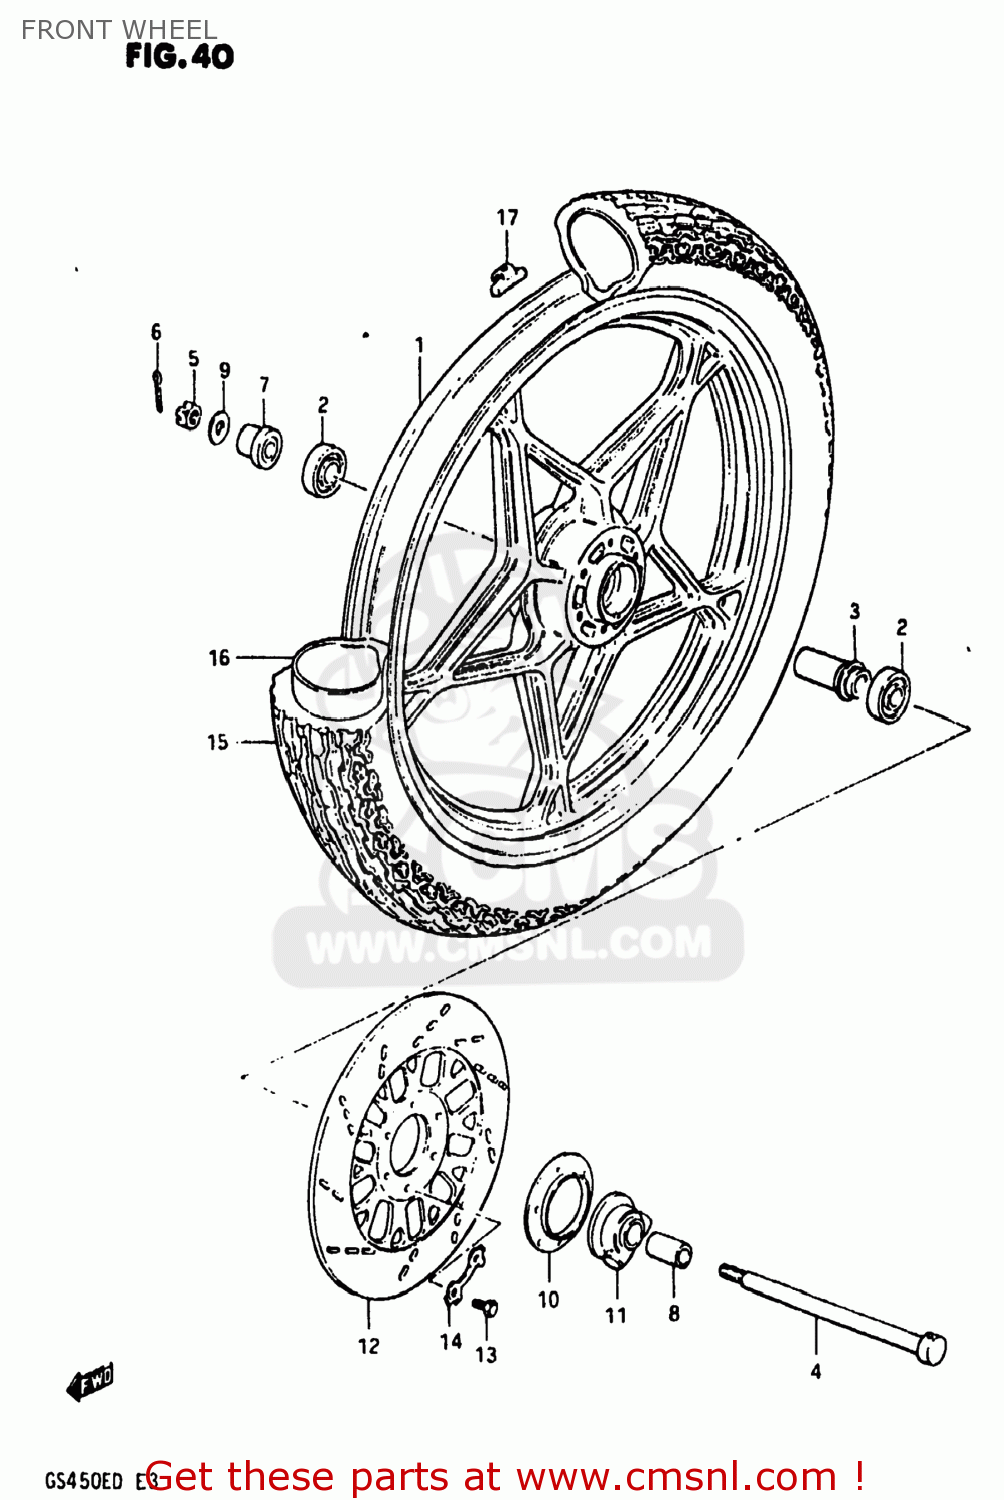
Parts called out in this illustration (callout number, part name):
1	WHEEL,FRONT
2	BEARING
3	SPACER(15.3X21.7X63)
4	AXLE,FRONT
5	NUT 12MM
6	COTTER PIN
7	SPACER,FR HUB BEARING,R
8	SPACER(15X22X30)
9	WASHER
10	DUST SEAL,SPEEDOMETER GEAR BOX
11	BOX ASSY,SPEEDOMETER GEAR
12	DISC,FR BRAKE
13	BOLT(8X25)
14	WASHER
15	TIRE,FRONT
16	TUBE,INNER
17	BALANCER,WHEEL
